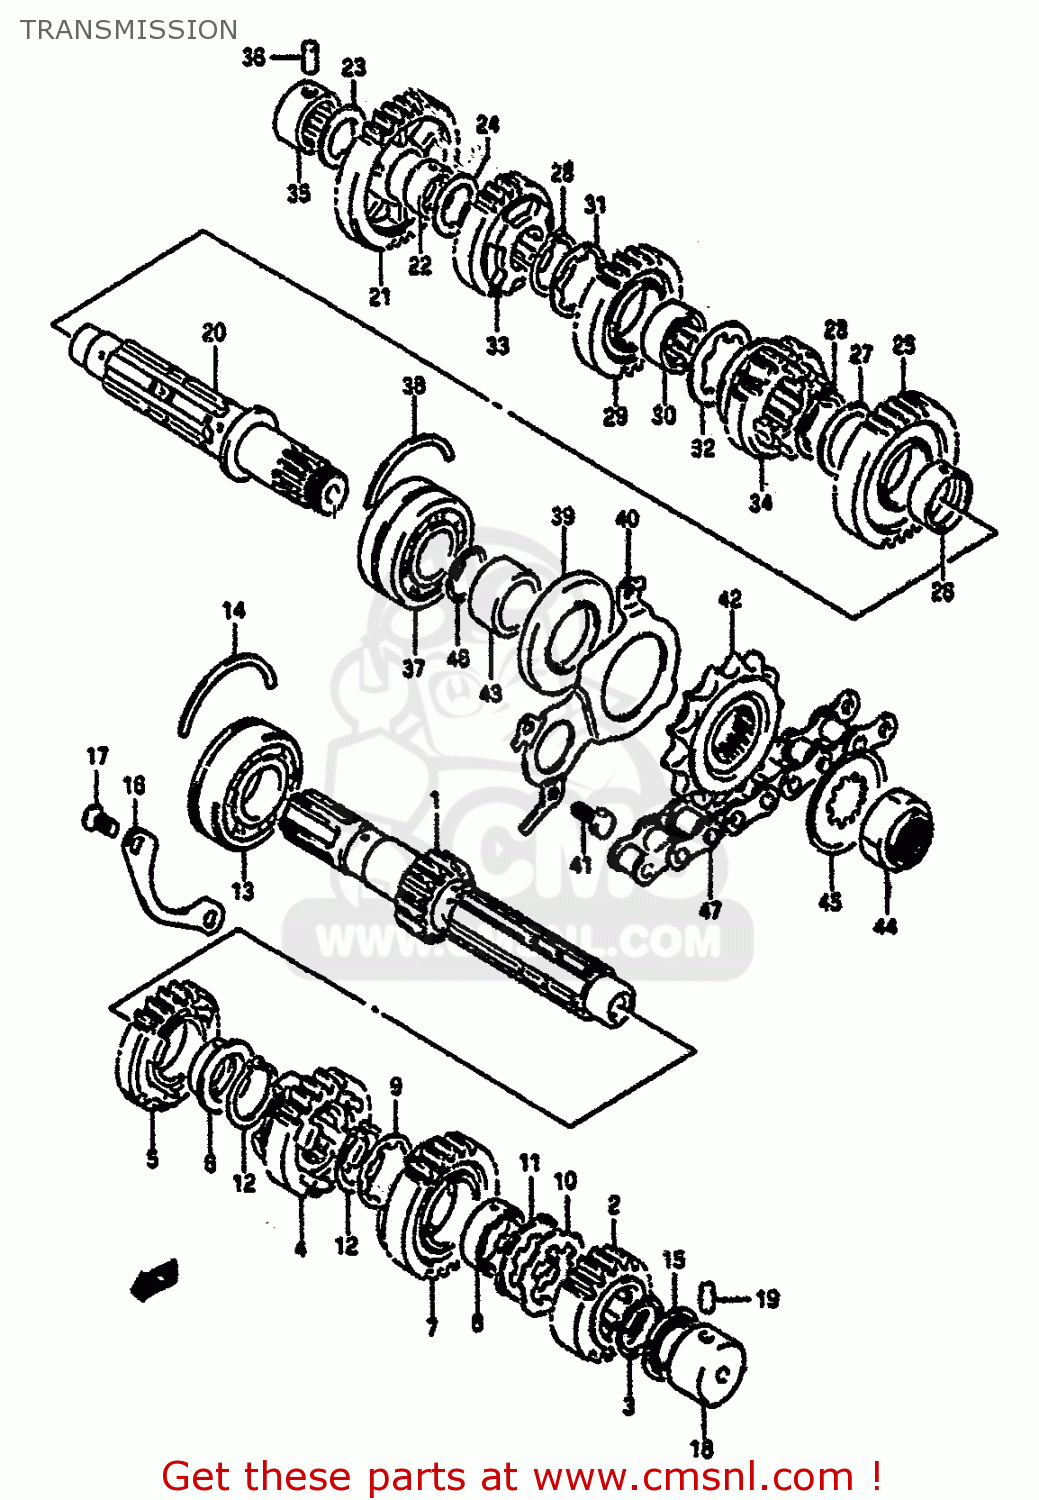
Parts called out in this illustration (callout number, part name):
1	SHAFT,COUNTER
2	GEAR,2ND DRIVE(NT:19)
3	CIRCLIP
4	GEAR,THIRD DRIVE (NT:20)
5	GEAR,FOURTH DRIVE (NT:22)
6	BUSHING
7	GEAR,FIFTH DRIVE (NT:23)
8	BUSH,5TH DRIVE GEAR
9	WASHER,LOCK
10	WASHER,LOCK
11	WASHER
12	RING,SNAP
13	BEARING(25X62X17)
14	C RING
15	SEAL,OIL(20X31.2X2.7)
16	RETAINER,CNTR SHAFT BEARING
17	SCREW
18	BEARING(20X34X17.5)
19	PIN
20	SHAFT,DRIVE
21	GEAR,FIRST DRIVEN
22	BUSHING
23	WASHER
24	WASHER
25	GEAR,SECOND DRIVEN
26	BUSH(28X32X11)
27	WASHER
28	CIRCLIP
29	GEAR,THIRD DRIVEN (NT:25)
30	BUSHING,THIRD DRIVEN GEAR
31	WASHER,LOCK
32	WASHER,LOCK
33	GEAR,FOURTH DRIVEN (NT:23)
34	GEAR,FIFTH DRIVEN
35	BEARING(20X34X20)
36	PIN
37	BEARING(25X62X21.6)
38	C RING
39	SEAL,OIL(34X62X6)
40	RETAINER,DRIVE SHAFT OIL SEAL
41	BOLT
42	SPROCKET,ENGINE(15T)
43	SPACER (25X34X18.1)
44	NUT
45	WASHER,LOCK
46	O RING(D:1,ID:24.5)
47	CHAIN,DRIVE(118LE)
